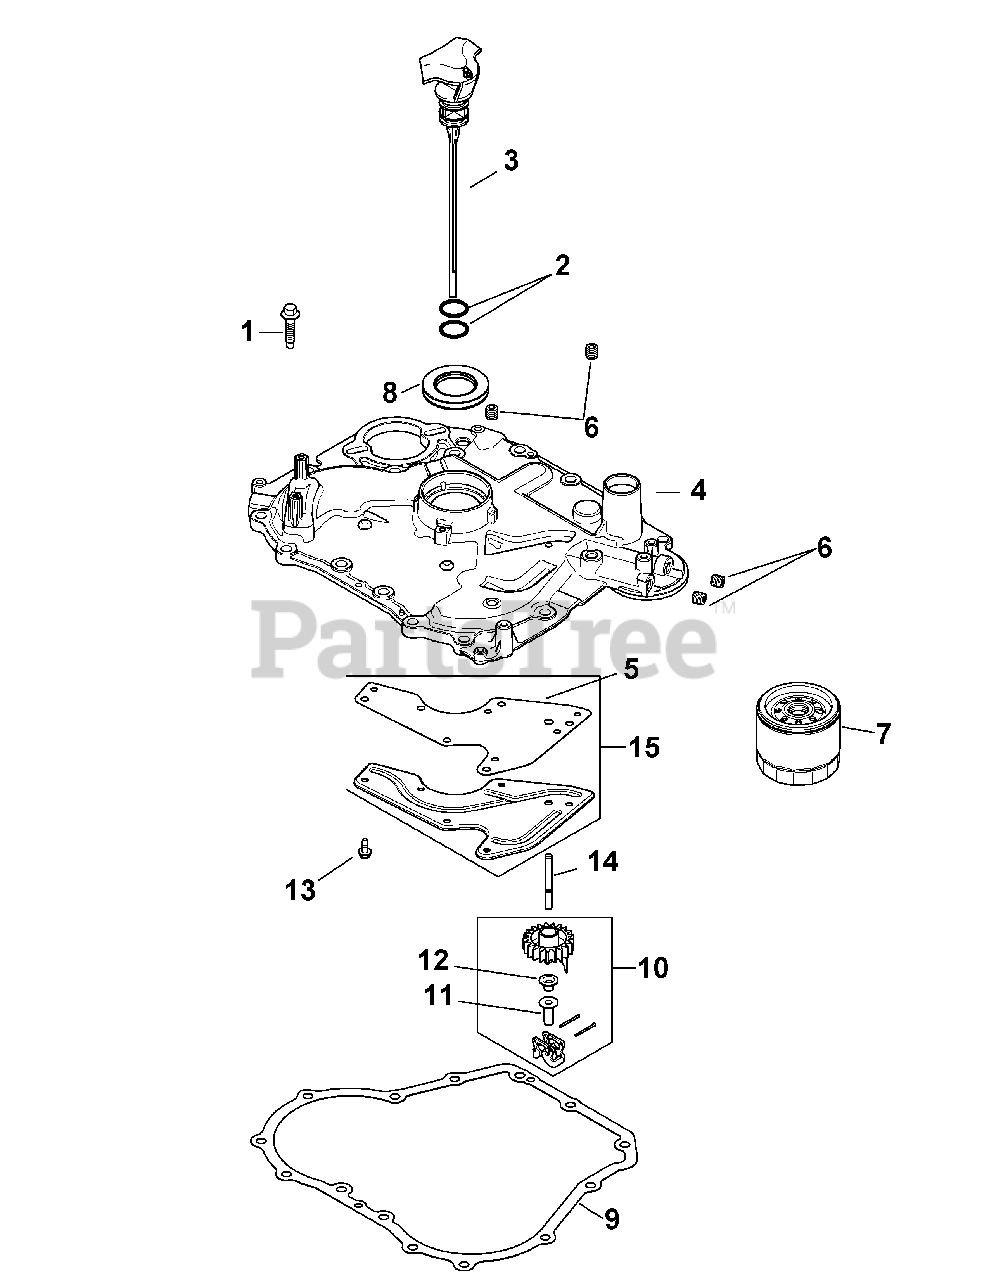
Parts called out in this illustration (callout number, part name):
1	Hex Flange Screw
3	Dipstick Ass’y-Std Yellow (Incl. 2)
4	Closure Plate Assembly
5	Oil Passage Gasket
6	Countersink Pipe Plug, 1/8
9	Closure Plate Gasket
10	Governor Gear Assembly (Incl. 11-12)
11	Governor Regulating Pin
12	Governor Regulating Pin
13	Flg. Thd. Frm. Screw, M5 X 0.8 X 13
14	Governor Cross Shaft
15	Oil Passage Cover Kit (Incl. 5)
